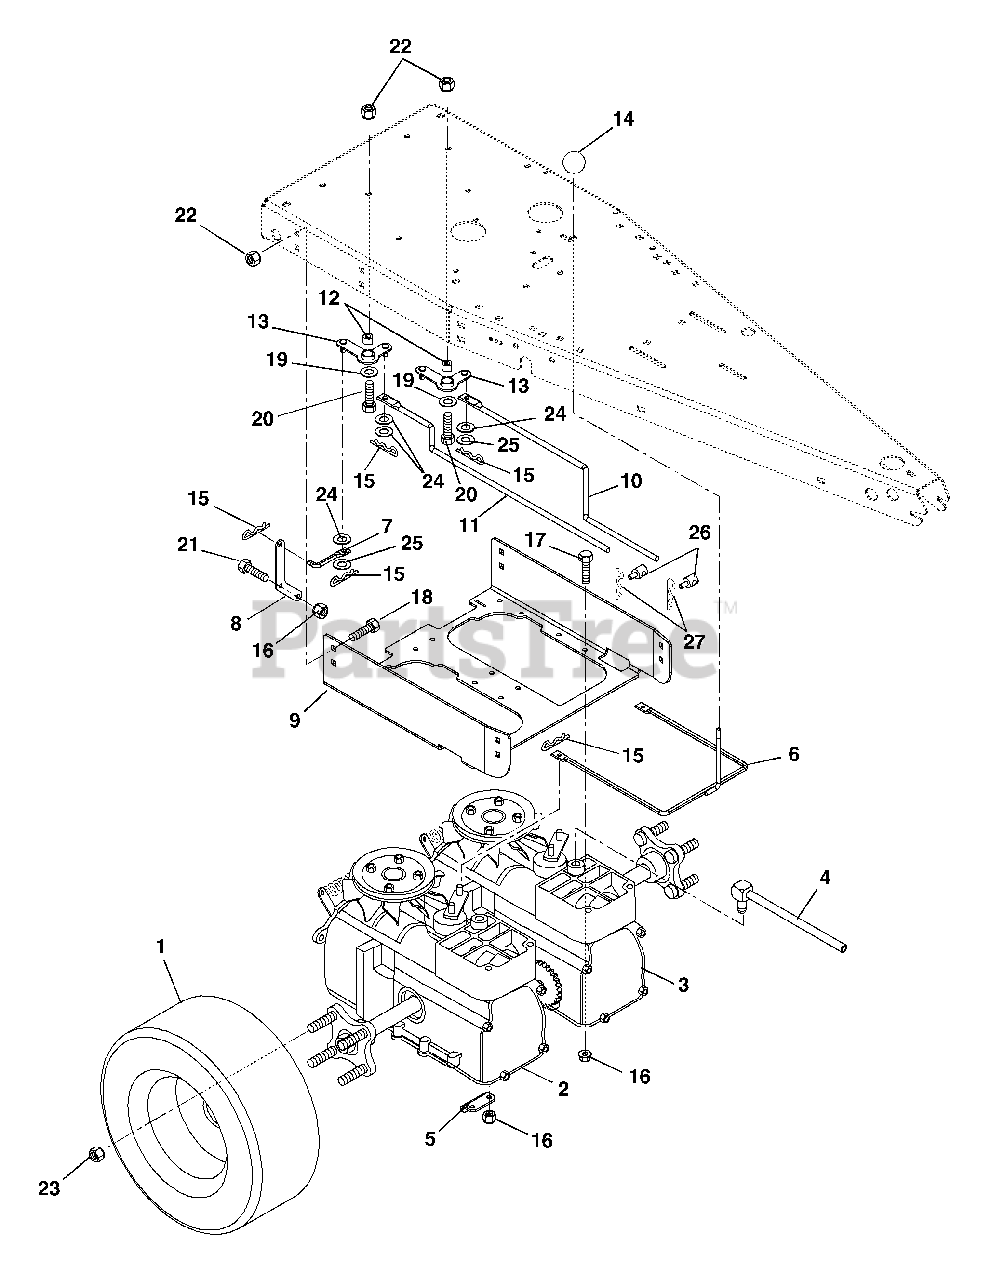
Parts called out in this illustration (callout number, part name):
1	Tire/Wheel Assembly 18 x 6.50-8 2 Ply (032)
1	Tire/Wheel Assembly 18 x 6.50-8 2 Ply (030)
2	Transaxle, Hydro Gear
3	Transaxle, Hydro Gear
4	Assembly, Breather
5	Bracket, Axle Support
6	Weldment, Dump Rod
7	Rod, Bell Crank
9	Cradle, Transmission
10	Rod, Steering Left Hand
11	Rod, Steering Right Hand
12	Bushing
13	Weldment, Bell Crank
15	Pin, Hair
16	Nut, Locking Top Flange .31-18
17	Bolt, Hex .31-18 x 2.50 Grade 5
18	Bolt, Round Head Square Neck .38-16 x .75 Grade 5
19	Washer, Flat Steel .38 x .875 x .083
20	Bolt, Hex .38-16 x 1.25 Grade 5
21	Bolt, Hex .31-18 x .75 Grade 5
22	Nut, Locking Top Flange .38-16
23	Nut, Lug .50-20
24	Washer, Flat Steel .38 x .87 x .179
25	Washer, Flat Steel .39 x .75 x .125
26	Trunnion, Brake
27	Pin, Hair
